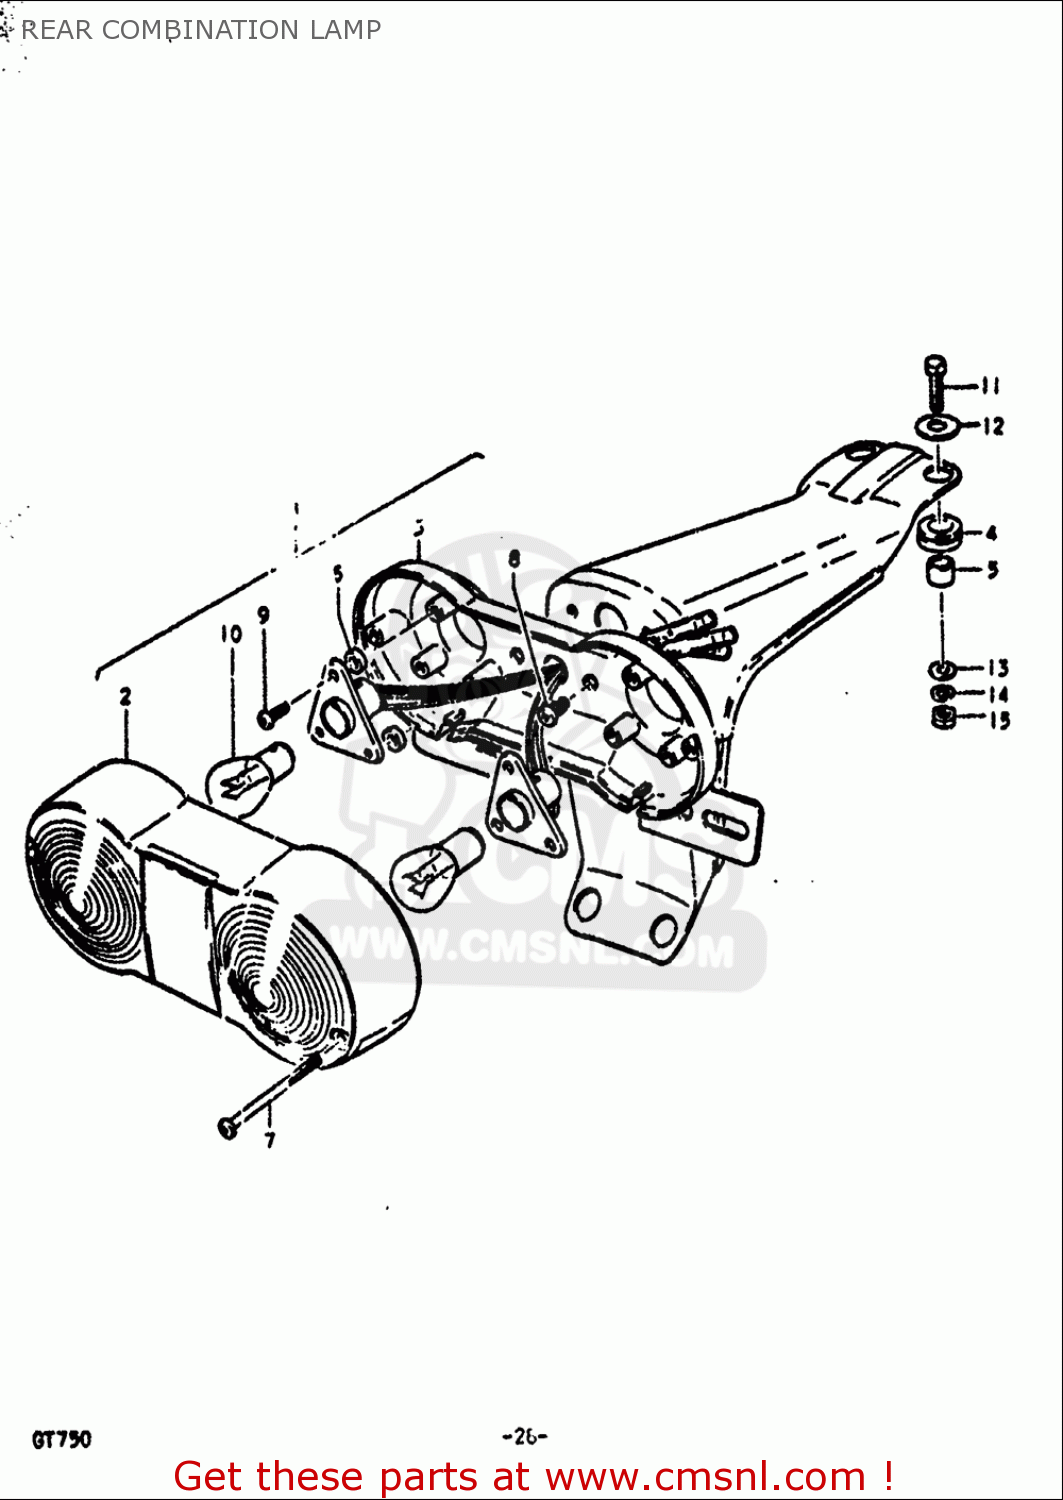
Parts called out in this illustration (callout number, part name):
2	LENS,REAR COMBINATION LAMP
4	CUSHION
5	SPACER
7	SCREW
8	SCREW
9	SCREW
10	BULB(12V23W)
11	BOLT 6X23
12	WASHER(6.5X20X1.6)
13	WASHER
14	WASHER,LOCK
15	NUT
